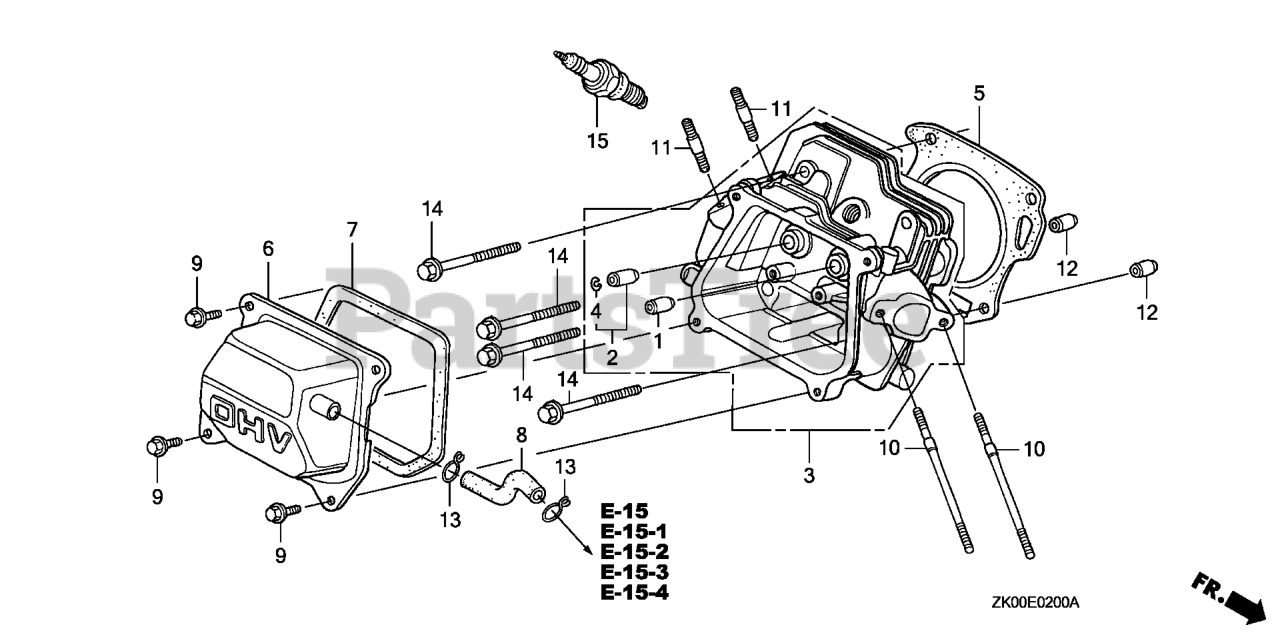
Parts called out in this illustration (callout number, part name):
3	CYLINDER HEAD
4	CLIP, VALVE GUIDE Use from Engine SN 1231803.
5	GASKET, CYLINDER HEAD (NIPPON LEAKLESS)
6	COVER, HEAD
7	GASKET, CYLINDER HEAD COVER
8	TUBE, BREATHER
9	BOLT, FLANGE (6X12) (CT200)
10	BOLT, STUD (6X109)
11	BOLT, STUD (8X32)
12	PIN A, DOWEL (10X16)
14	BOLT, FLANGE (8X60)
15	SPARK PLUG (BPR5ES) (NGK)
15	SPARK PLUG (W16EPR-U) (DENSO)
15	SPARK PLUG (BPR6ES) (NGK)
15	SPARK PLUG (W20EPR-U) (DENSO)
